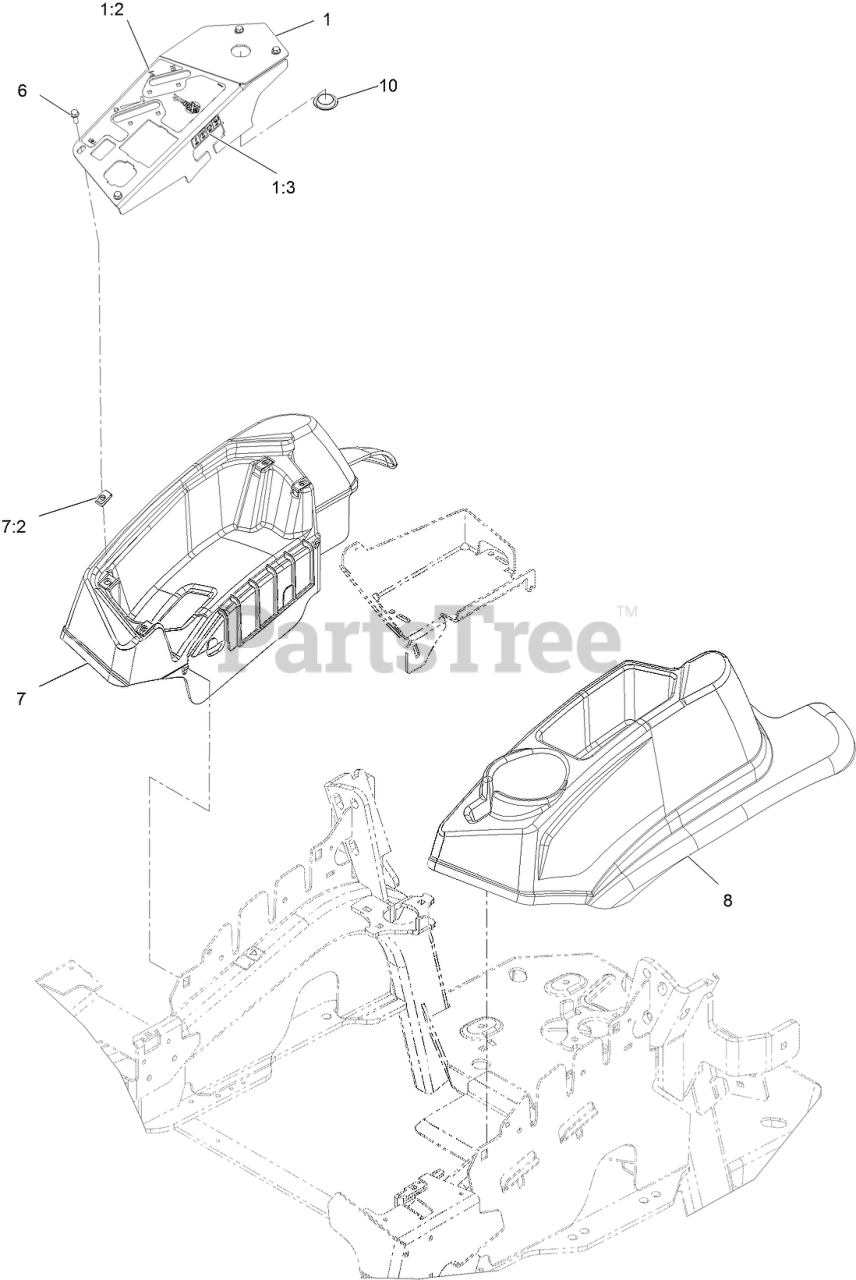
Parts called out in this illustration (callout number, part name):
1	CONSOLE,PANEL W/DECAL
1:2	DECAL-CONTROL PANEL NON-EFI
1:3	DECAL-FUSES
6	SCREW-HWH
7	CONSOLE,RH AS ASM
8	CONSOLE, LH AS
10	PLUG-PLASTIC
